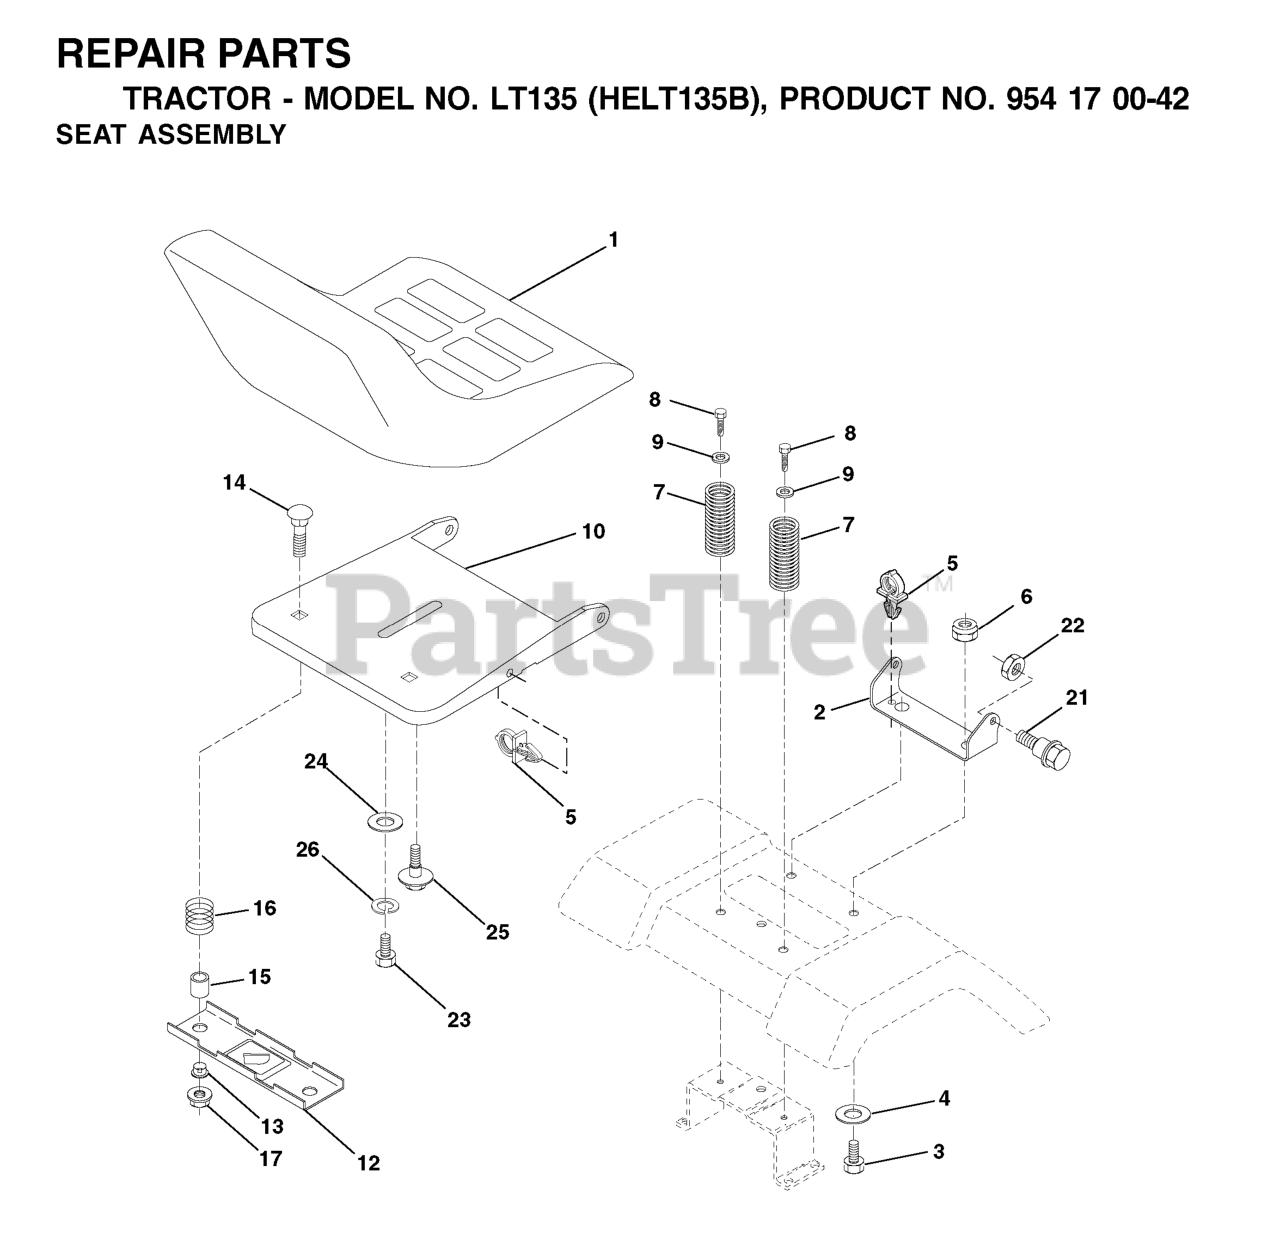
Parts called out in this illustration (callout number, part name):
1	SEAT, GRAY
2	SEAT PIVOT BRKT
3	BOLT, HEX 3/8-16X1
6	NUT
7	SPRING COMPRESSION
8	SCREW 3/8-16X1
9	WASHER
10	PAN, SEAT
12	BRKT SWITCH
14	BOLT.ROUND.HEAD.SQUARE.NECK
15	SPACER SPLIT 28X.96
17	NUT T
21	BOLT.SHOULDER.5/16-18
22	NUT.71038.31-18.HEX.NYLOCK
23	BOLT.HEX.BLACK
25	BOLT,SHOULD
26	LOCKWASHER
